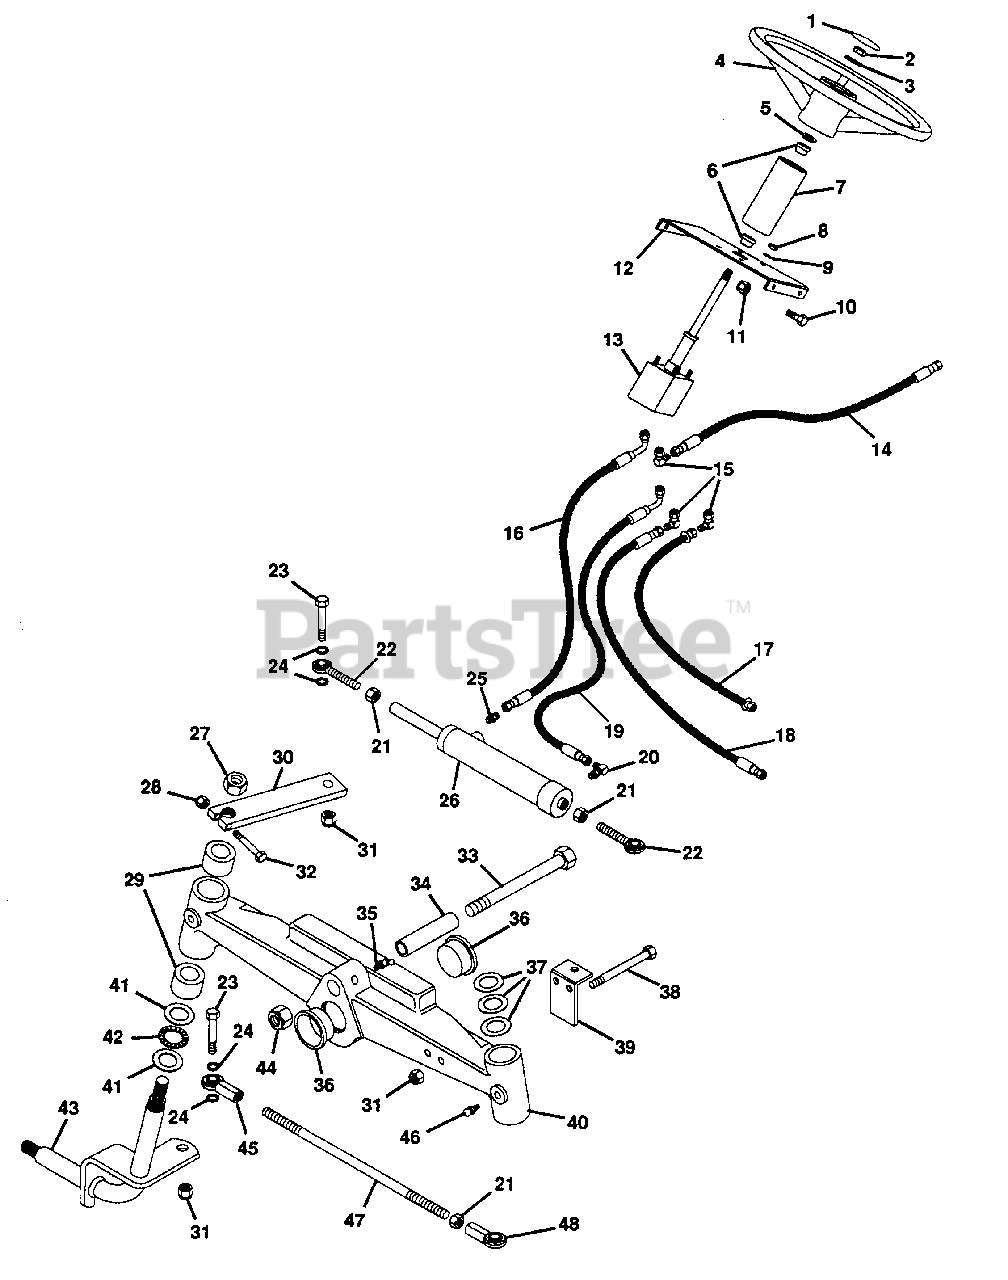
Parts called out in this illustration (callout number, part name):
1	CAP, STEERING WHEEL
2	NUT, JAM 5/8-11 HEX
3	WASHER, FLAT .656X1.312X.095
4	WHEEL, STEERING
5	SPRING, COMP. 1X.80X36 LB/LN
6	BUSHING, NYLON .760X1.00X.60 FLG
7	BUSHING, STEERING WHEEL
8	NUT, HEX 5/16-24
9	WASHER, LOCK 5/16 REG,
10	BOLT, HEX 5/16-18X.75
11	NUT, LOCK 5/16-18
12	BRACKET, POWER STEERING SUPPORT
13	POWER STEERING UNIT
14	HOSE, PSU TO SC RELIEF VALVE
15	ADAPTER(P.H. 3903-6-6)
16	HOSE, PSU TO SC RIGHT
17	HOSE, PSU TO SC TANK
18	HOSE, PSU TO SC LIFT VALVE
19	HOSE, PSU TO SC LEFT
20	ADAPTER(P.H. #2503-6-6)
21	NUT, JAM 1/2-20
22	ASSEMBLY, ROD END(R.H.)
23	BOLT, HEX 1/2-13X2.00
24	SPACER, .500X.625X.125
25	ADAPTER(P.H.#0503-6-6)
26	CYLINDER, STEERING
27	NUT, HEX 5/8-11
28	NUT, LOCK 5/16-24
29	BUSHING, .877X1.004X1.0
30	ARM, TIE ROD
31	NUT, LOCK 1/2-13
32	BOLT, HEX 5/16-24X1.75
33	BOLT, HEX 3/4-10X4.5
34	TUBE, AXLE PIVOT
35	FITTING, LUBE 45 DEG.
36	CAP, FRONT AXLE
37	WASHER, FLAT .812X1.496X.134
38	BOLT, HEX 1/2-13X3.50
39	BRACKET, STEERING CYLINDER
40	AXLE, STEERING
41	RACE, BEARING THRUST
42	BEARING, NEEDLE THRUST
43	WELDMENT, KING PIN(R.H.)
43	WELDMENT, KING PIN(L.H.)
44	NUT, LOCK 3/4-10
45	ROD END, STEERING L.H.
46	FITTING, LUBE 1/4-28
47	TIE ROD
48	ROD END, STEERING R.H.
